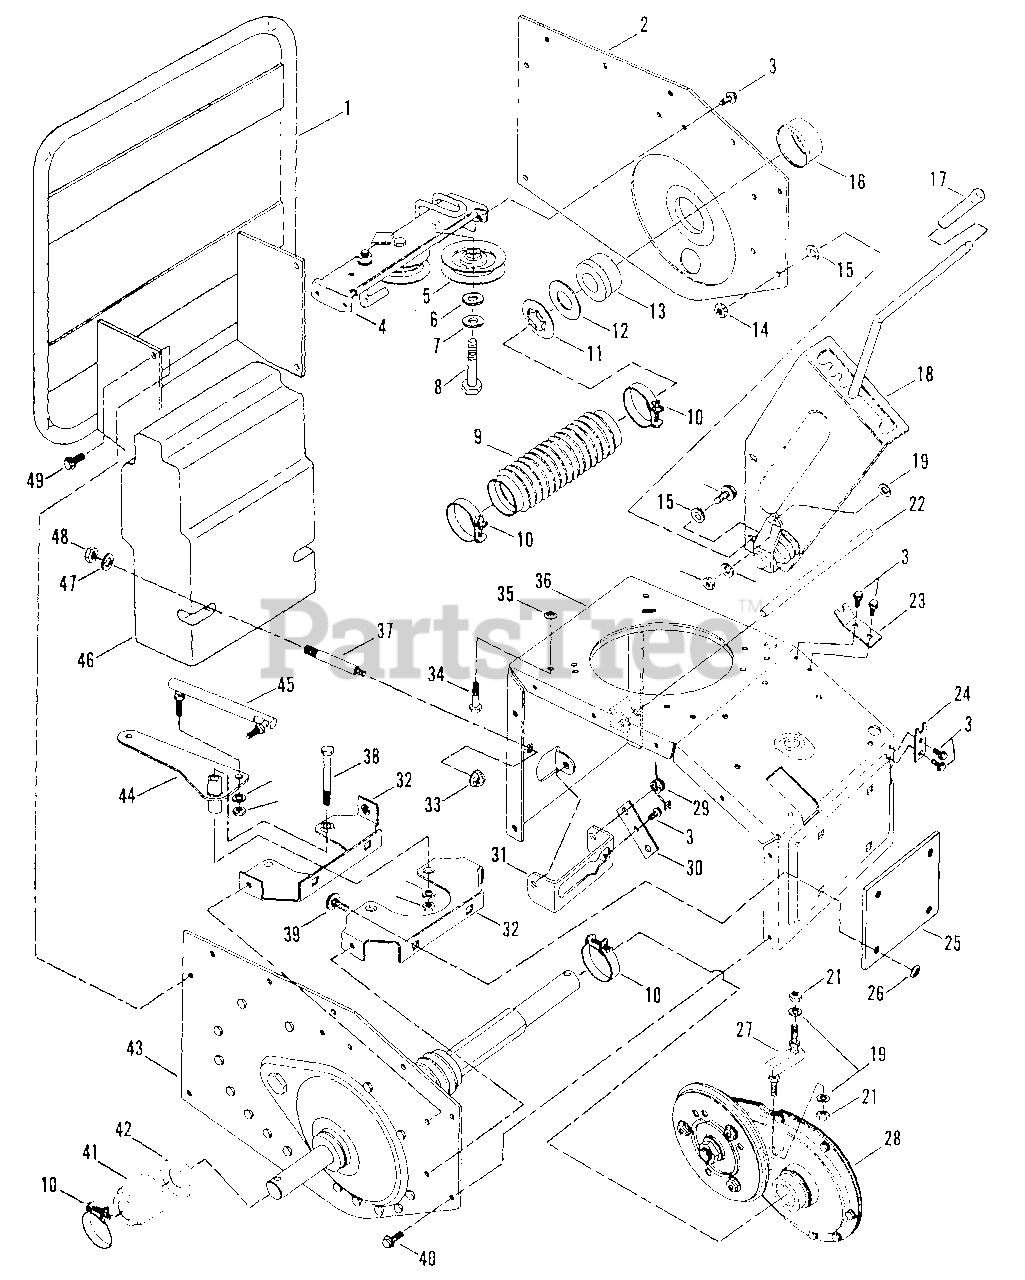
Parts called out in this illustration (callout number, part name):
1	BAR, Stand-Up
2	FRAME, Right Side
3	SCREW, 1/4-20 x 3/8" Self-Tapping
4	ASSEMBLY, Idler Bracket
5	PULLEY, V-Idler 2.62" OD
6	WASHER, 3/8" Flat
7	WASHER, 3/8 Split Lock
8	SCREW, 3/8-16 x 1 1/2" Hex Head Cap
9	SEAL, Long
10	CLAMP, 1-7/8"
11	WASHER, Thrust
12	WASHER, Thrust (Nylon)
13	BEARING, Axle
14	NUT, 5/16-18 Hex Lock
15	WASHER, 5/16 Internal/External Tooth Lock
16	CAP, Seal L.H. 3/4"
17	GRIP
18	ASSEMBLY, Shift Quadrant
19	WASHER, 5/16 Split Lock
20	SCREW, 5/16-18 x 1" Self-Tapping
21	NUT, 5/16-24 Hex
22	(NLA) ROD
23	(NLA) CLIP, Cable
24	(NLA) CLIP, Control
25	(NLA) SPACER, Tiller Head
26	RETAINER, Bolt 3/8"
27	LINK, Short Shift 1"
28	ASSEMBLY, Primary Chain Case
29	(NLA) SPRING
30	(NLA) LEVER
31	YOKE, Clutch
32	BRACE
33	NUT, 5/16-18 Hex Flange Lock
34	SCREW, 5/16-18 x 1 1/2" Hex Flange Lock
35	RETAINER, Bolt 5/16"
36	FRAME
37	STUD, Weight
38	BOLT, 5/16-24 x 3" Shoulder
39	BOLT, 3/8-16 x 1" Carriage
40	SCREW, 5/16-18 x 1/2" Self-Tapping
41	BOOT
42	SEAL, OIL .750" ID x 1.832" OD
43	ASSEMBLY, Left Frame Drive (RT5)
43	(NLA) ASSEMBLY, Left Frame Drive (RT8 & 5X)
44	BELLCRANK, Shift
45	LINK, Shift 4.5"
46	(NLA) WEIGHT
47	WASHER, 7/16 Flat
48	NUT, 7/16-14 Hex Lock
49	SCREW, 3/8-16 x 1" Self-Tapping
